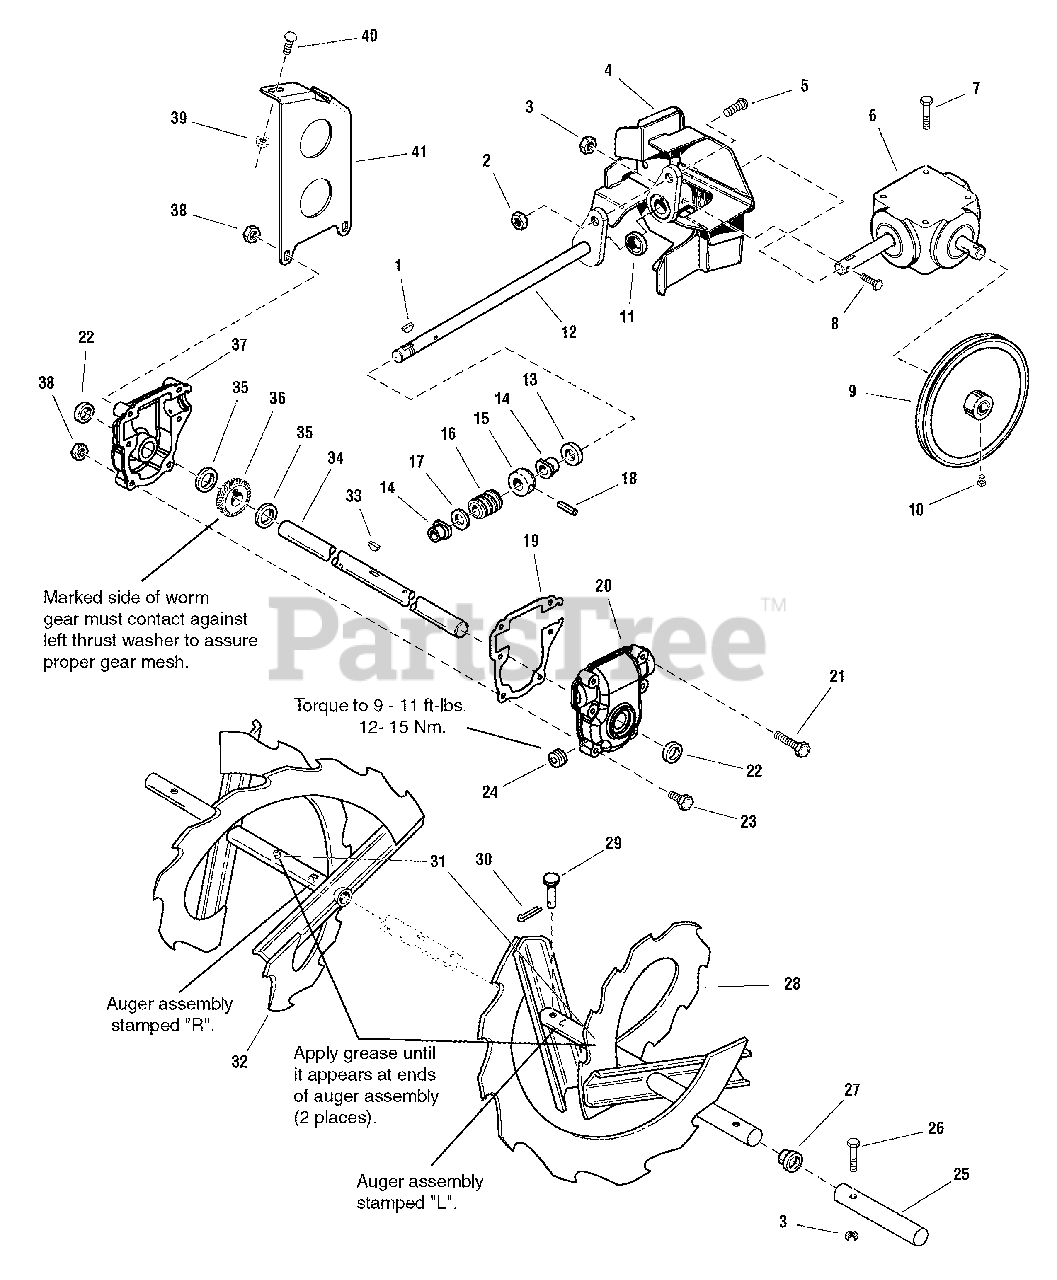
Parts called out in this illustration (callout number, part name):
1	KEY, Woodruff, 47/250 x 5/8
2	NUT, Hex Nylock, 5/16-18
3	NUT, Hex Lock ESNA Light, 1/4-20NC-3B
4	IMPELLER ASSEMBLY
5	CARRIAGE BOLT, 5/16-18 x 1
6	GEARBOX ASSEMBLY
7	CAPSCREW, Whiz, 3/8-16 x 3/4
8	CAPSCREW, 1/4-20 x 1.88
9	PULLEY, Input
10	SCREW, Set Square Head Cup Point, 5/16-18 x 1/2 G8
12	SHAFT ASSEMBLY, Worm
13	SEAL, Oil 1/4" Thick
14	BUSHING, 377/500 ID x 1-1/10 OD x 1-1/100 LG Powerdered Metal
15	COLLAR, Thrust 3/4 LG
16	GEAR, Worm 1-3/8 LG
17	WASHER, Thrust
18	PIN, Drive Lock Type A 3/16 x 1-1/2
19	GASKET, Gear Case
20	CASE, Gear L.H.
21	CAPSCREW, Hex Head, 1/4-20 x 2-1/2 G5
22	SEAL, Oil, 1/4" Thick
23	CAPSCREW, Hex Head, 1/4-20 x 2-1/4 G5
24	FITTING, Pipe Plug, Square Head
25	SHAFT, E-Coat, 5 LG
26	CAPSCREW, Hex Head, 1/4-20 x 1-3/4 G5
27	BUSHING, Plastic
28	AUGER ASSEMBLY, L.H.
29	PIN, Flat Head Drilled
30	PIN, Cotter 47/50 x 3/4
31	FITTING, Lube 1/4 Drive, No Check Ball
32	AUGER ASSEMBLY, R.H.
33	KEY, Woodruff 1/4 x 3/4
34	SHAFT, 16 LG Auger 3 Holes
35	WASHER, Thrust
36	GEAR, Worm 7/8 LG
37	CASE, Gear R.H.
38	NUT, Hex Flange, 1/4-20 Toplock Small
39	NUT, Hex Flange, 5/16-18, Whiz Lock Small
40	CARRIAGE BOLT, 5/16-18 x 3/4 G5
41	SUPPORT, Gear Box 10GA
